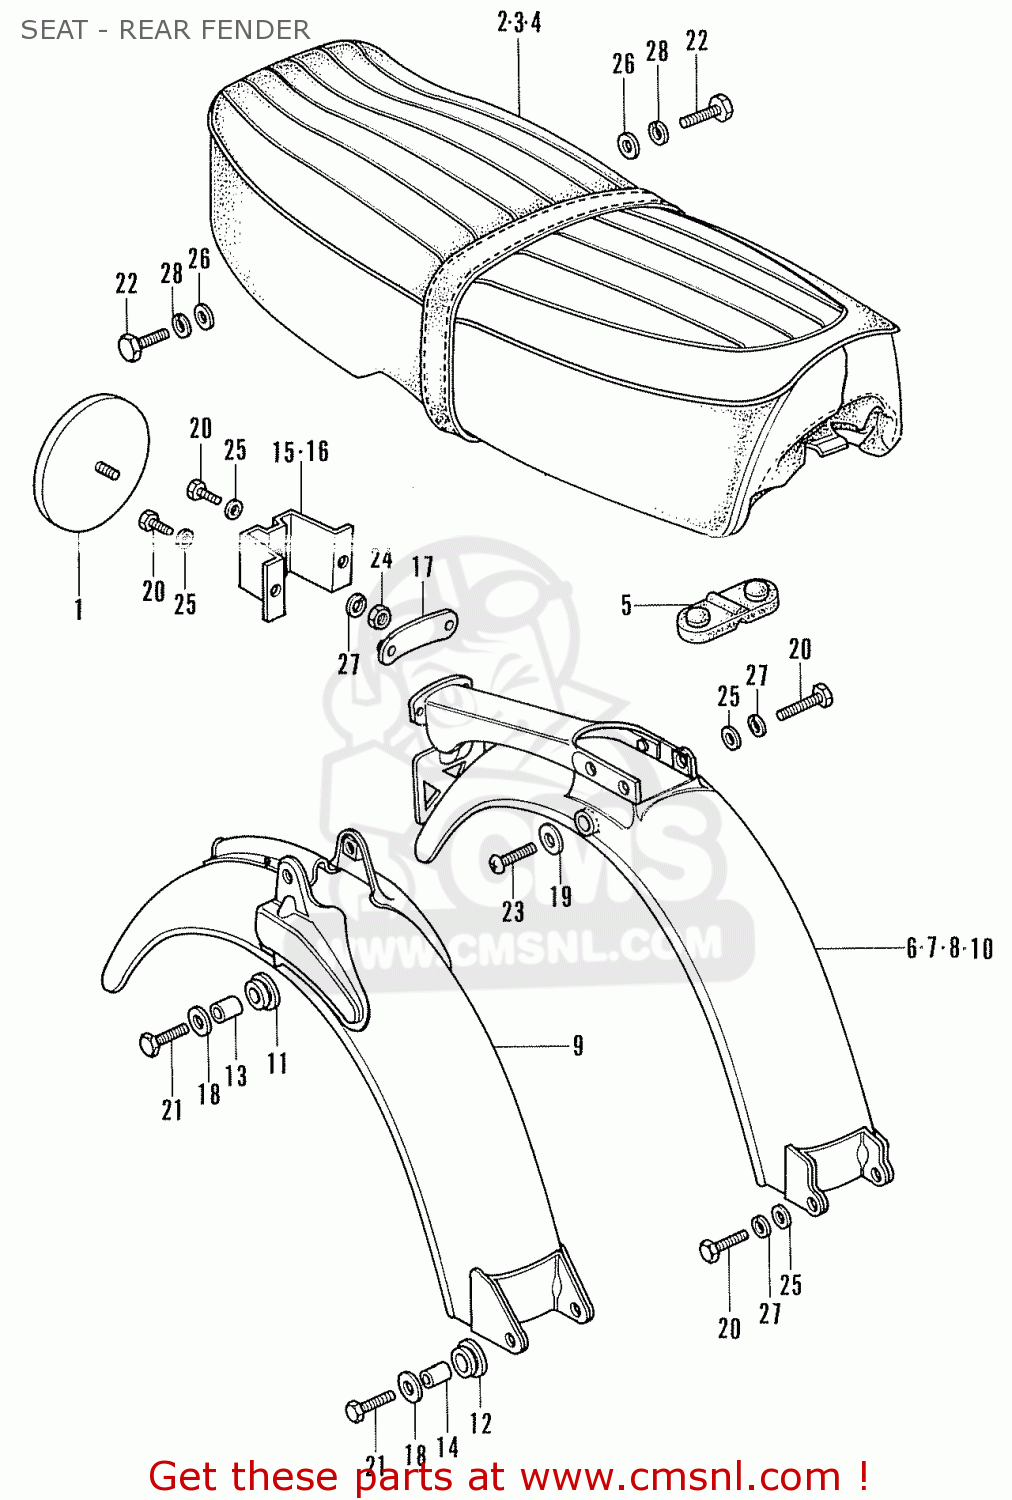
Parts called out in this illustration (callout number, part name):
2	SEAT,DUAL
5	RUBBER. SEAT. SET
8	FENDER, REAR
19	WASHER 6.5X19
20	BOLT,HEX 6X12
22	BOLT,HEX 8X16
23	SCREW,CROSS,6X10
25	WASHER,PLAIN, 6MM
26	WASHER,PLAIN,8MM
27	WASHER,SPRING,6MM
28	SPG-WASHER 8MM
